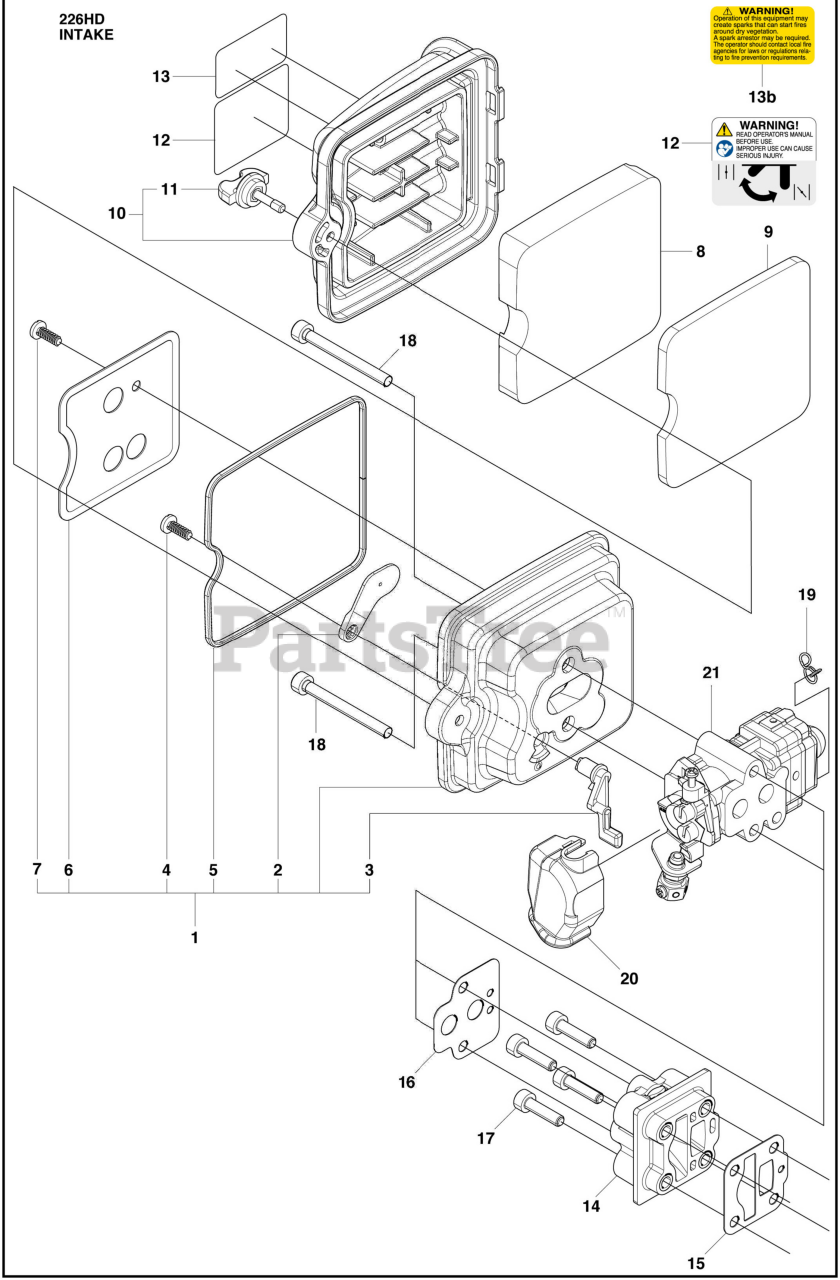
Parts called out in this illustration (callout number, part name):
2	Choke Plate
3	Choke Lever
4	Screw
7	Screw
8	Air Filter, Foam
9	Air Filter
10	Cover Assembly
14	Insulator
15	Insulator Gasket
16	Carburetor Gasket
18	Bolt
19	Clip
20	Cover
21	Carburetor Assembly
